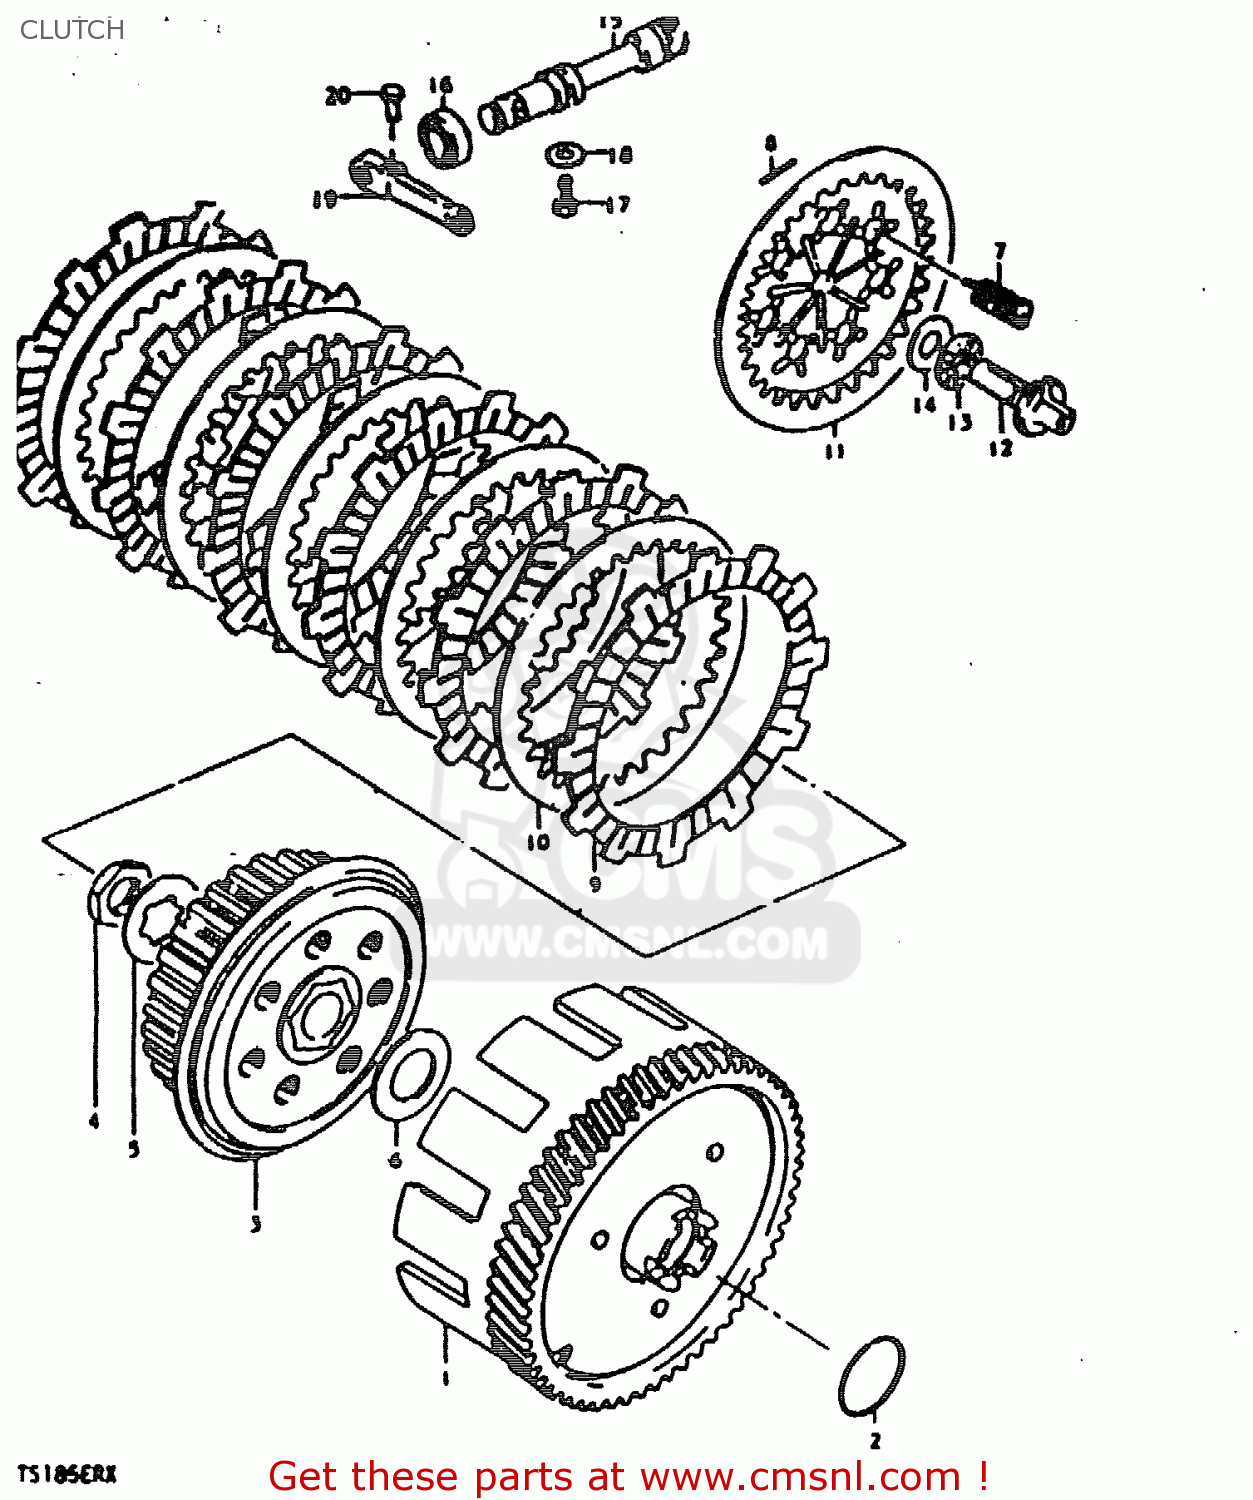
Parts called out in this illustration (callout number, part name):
1	GEAR ASSEMBLY,PRIMARY DRIVE
2	SPRING
3	HUB,CLUTCH SLEEVE
4	NUT
5	WASHER,LOCK
6	WASHER
7	SPRING
8	PIN(2.5X19.8)
9	PLATE,CLUTCH DRIVE
10	PLATE,CLUTCH DRIVEN (NAS)
11	PLATE,CLUTCH PRESSURE
12	RACK,CLUTCH RELEASE
13	BEARING(10X22X2.8)
14	WASHER(10.1X21.4X0.8)
15	PINION,CLUTCH RELEASE
16	OIL SEAL
17	BOLT(6X12)
18	WASHER
19	ARM,CLUTCH RELEASE
20	BOLT
